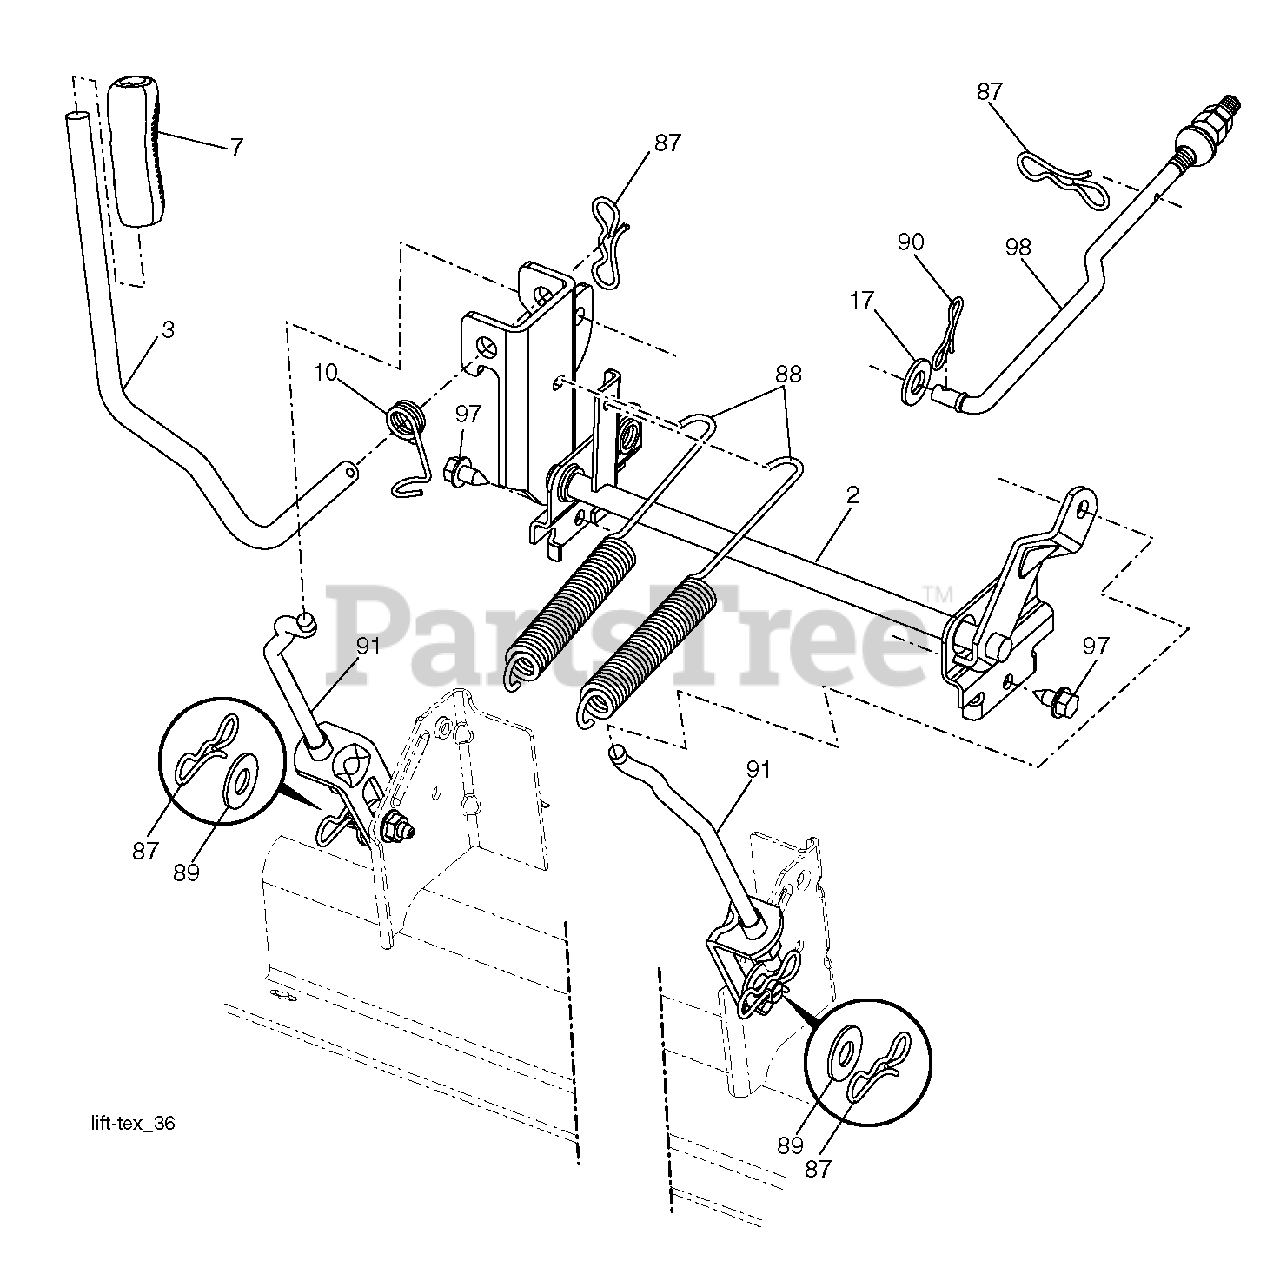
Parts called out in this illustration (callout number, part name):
2	SHAFT.ASM.CROSS.LIFT
3	LEVER.LIFT.HANDLE.GT
7	GRIP.HANDLE.LIFT.PVC.BLACK
10	SPRING.TORSION.LIFT.HANDLE
17	WASHER
87	PIN.COTTER.7/16.BOW TI.
88	SPRING.LIFT.ASSIST.GT2
89	WASHER.CLEAR.ZINC
90	PIN.COTTER.5/16.BOW TI
91	LINK.ASM.LIFT.54"TG
97	SCREW, 3/8-16X3/4
98	LINK.ASM.SUSP.FRONT.MWR.10.5
